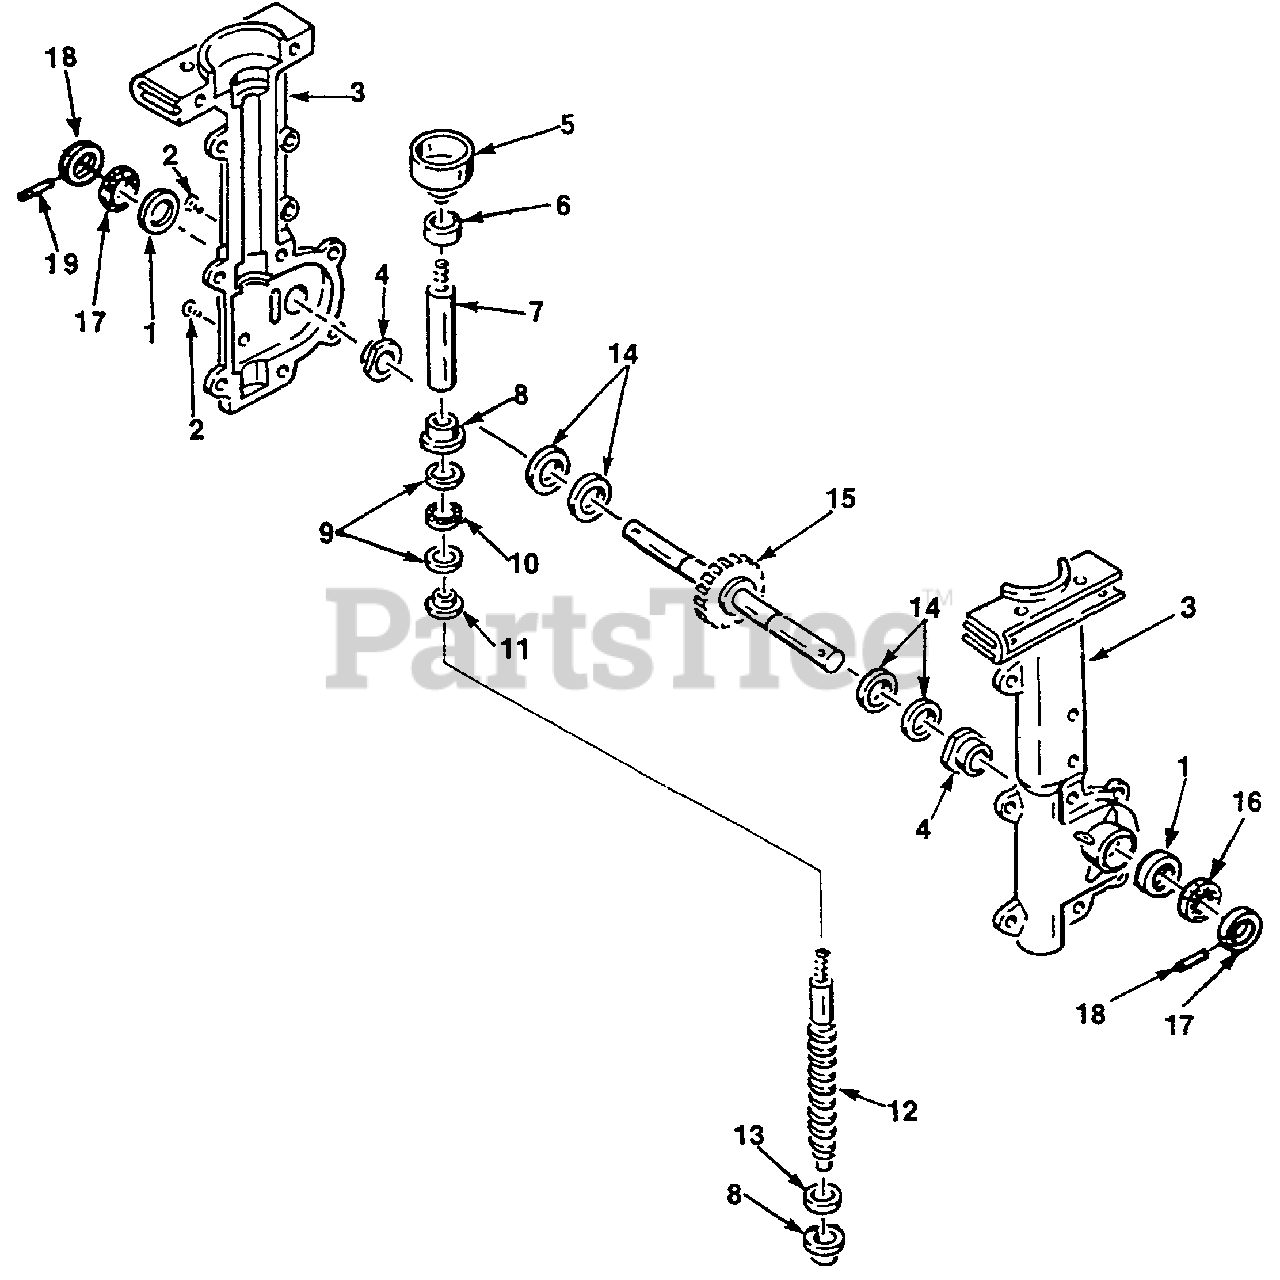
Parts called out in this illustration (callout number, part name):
1	SEAL- Lip (3/4")
2	SCREW- Slotted hex hd. (1/4-20 x 1/2")
3	TRANSMISSION ASSEMBLY
4	BUSHING- Bronze (3/4" I.D.)
5	DRUM & HUB (Clutch)
6	BEARING- Roller
7	SHAFT- Connecting
8	BUSHING- Bronze (7/16")
9	WASHER- Thrust hardened
10	BEARING- Needle (thrust)
11	WASHER- Adaptor
12	SHAFT- Worm (3/4 x 7/16-16) (16P)
13	WASHER- Thrust (3/4 x 7/16")
14	WASHER- Thrust (16 x 3/4 x 1 1/2")
15	SHAFT- Tine, w/Worm Wheel
16	WASHER- Felt seal (1/8 x 3/4 x 1 1/4")
17	DIRT CAP
18	SCREW- Set (#10-32 x 1/4") Metal Dirt Cap
